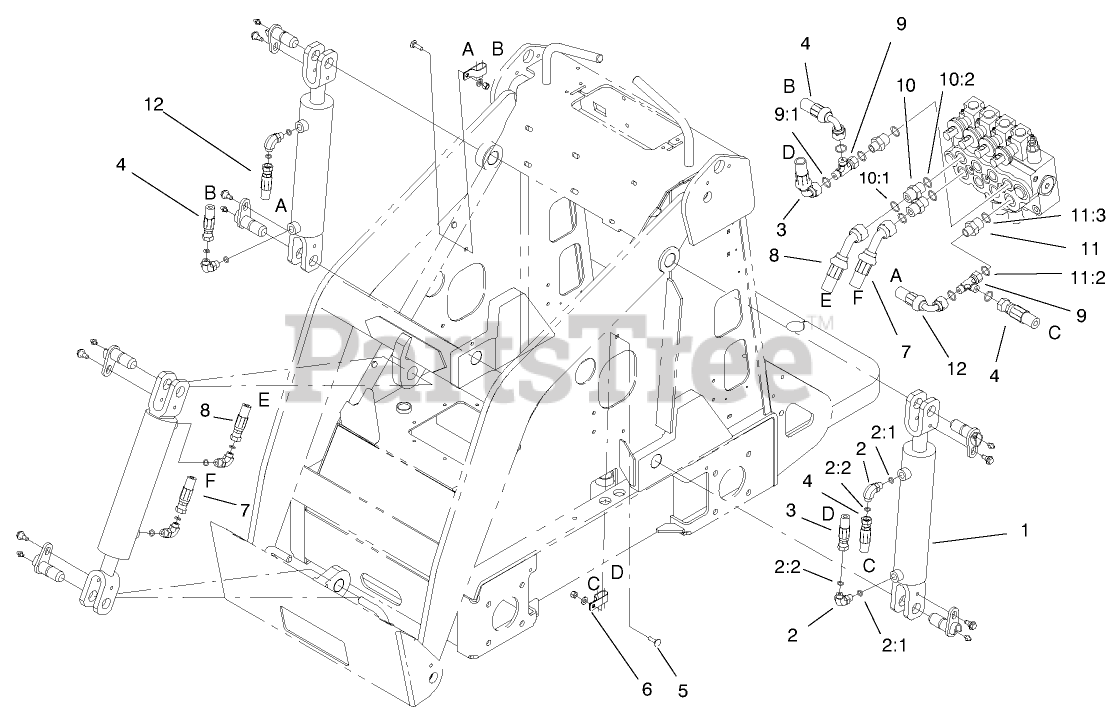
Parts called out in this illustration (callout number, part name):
1	CYLINDER KIT
2	FITTING-ELBOW 90
2:1	O-RING
2:2	O-Ring
3	HYD HOSE ASM
4	HOSE-HYD
5	BOLT-CARR
6	CLAMP-R, DOUBLE
7	HOSE-HYD
8	HOSE-HYD
9	FITTING-HYD
9:1	O-Ring
10	FITTING-STRAIGHT
10:1	O-RING
10:2	O-RING
11	FITTING-STR
11:2	O-RING
11:3	O-Ring
12	HYD HOSE ASM
